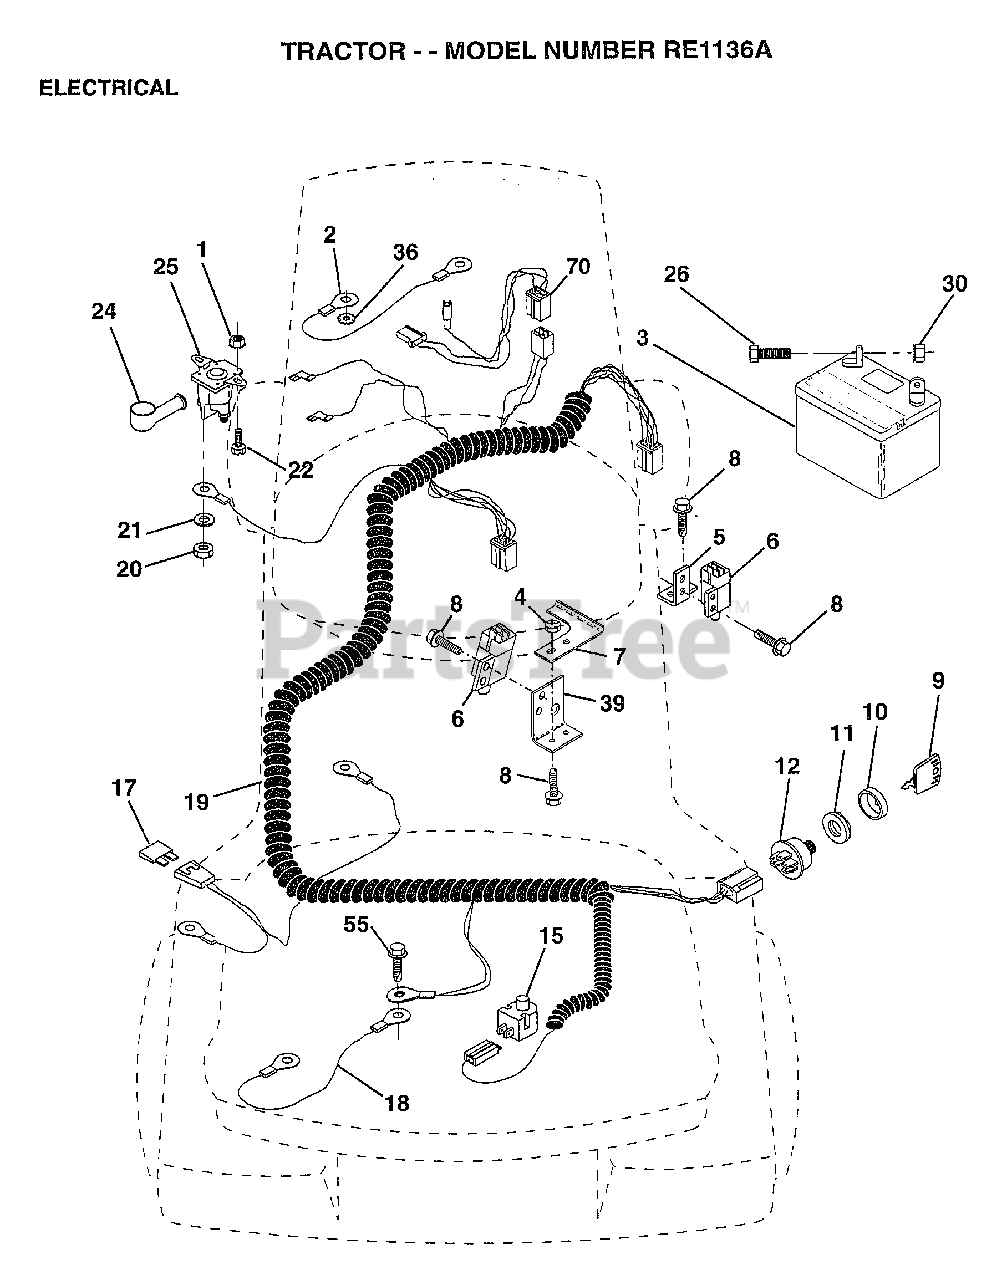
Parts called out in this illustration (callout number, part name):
1	NUT HXKEP 1/4X20
2	CABLE ASM.
4	LOCKNUT
5	BRACKET LT
6	SWITCH INTERLOCKT
7	KEEPER.ACTUAT.LR.
8	SCREW
9	KEY STEEL DELTA
10	COVER KEY SWITCH
12	SWITCH.IGNITION
15	SWITCH SEAT
17	FUSE HYT
18	CABLE ASSY
19	HARNESS.IGNITION
20	NUT
22	BOLT HXHD FIN
26	BOLT LT
30	NUT
36	LOCKWASHER
39	BRACKET SWT CLUTC
55	SCREW LT
70	HARNESS.ENGINE
